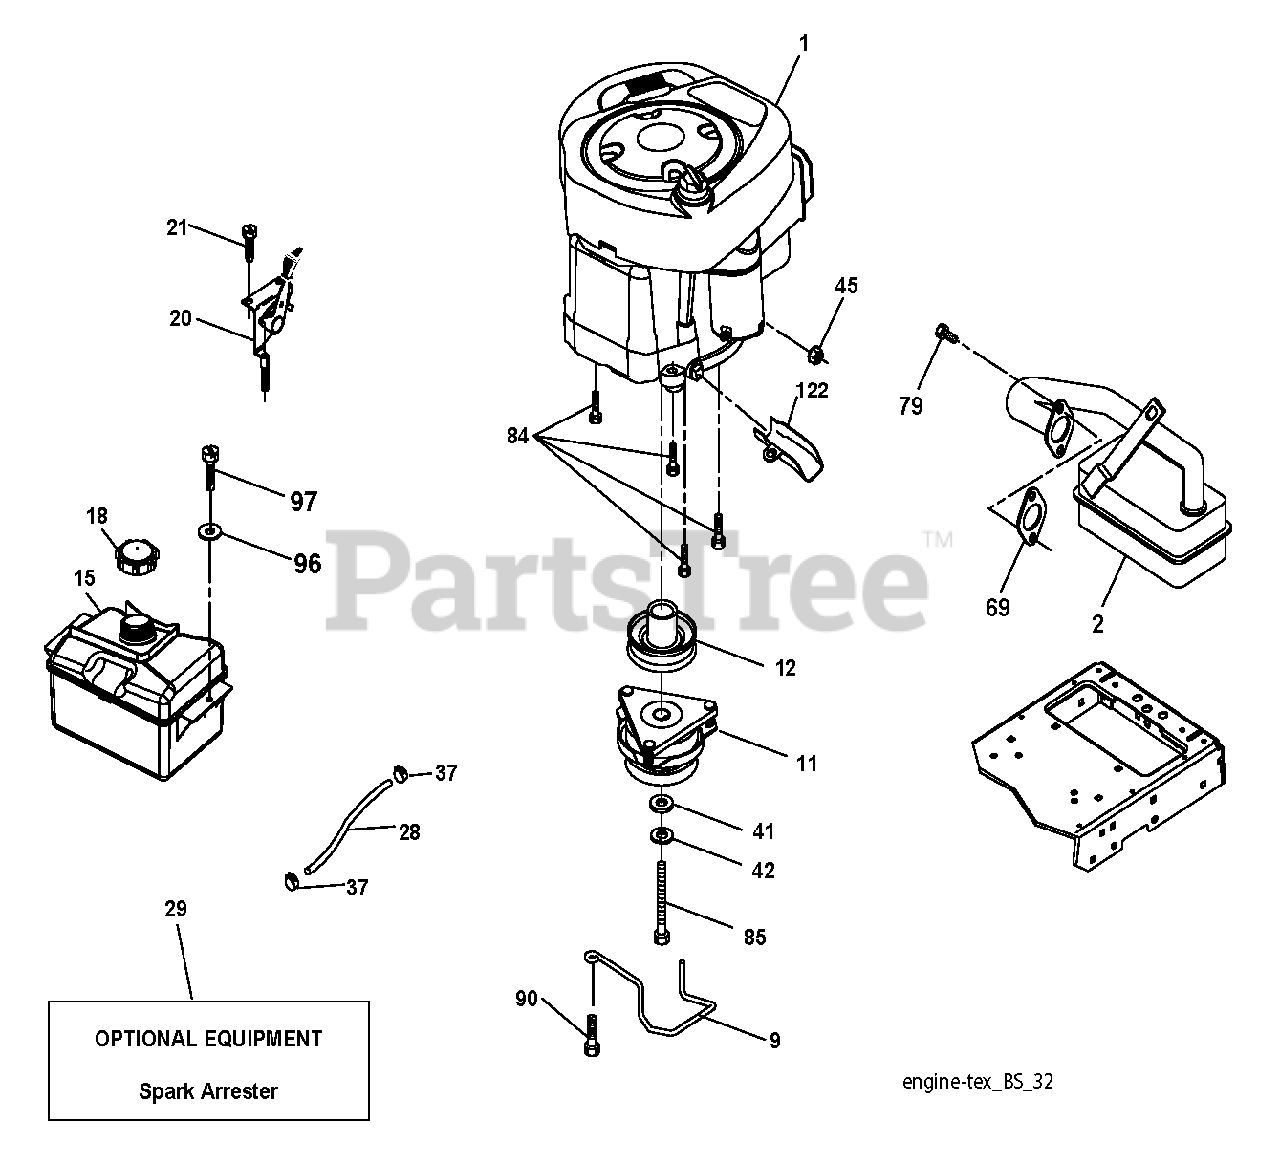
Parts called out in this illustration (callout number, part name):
2	MUFFLER.B&S.MODEL.21.11HP.OHV
9	KEEPER.BELT.ENGINE.3.25 (3 2)
11	RB.CLUTCH.OGURA.4.4.PD
12	PULLEY.ASM.ENG.OGURA.3
15	FUEL.TANK.ASM.NON-EPA
18	CAP ASM.FUEL.2.25"FR.
20	CONTROL.TH/CK.C.
21	SCREW.#10 X 0.750.BOS
28	LINE.FUEL.20
29	KIT.SPARK ARRESTOR 794945 B&S
37	HOSE CLAMP
42	LOCKWASHER
45	NUT
69	REPL BY 532 27 22-93
79	SCREW.SOCKET HD.5/16-1
84	SCREW.3/8-16
85	BOLT HEX 7/16-20X4-1/4"
90	SCREW 3/8-16X1
97	SCREW HEXWSHR 1/4-20X3/4
122	EXTENSION DRAIN OIL
